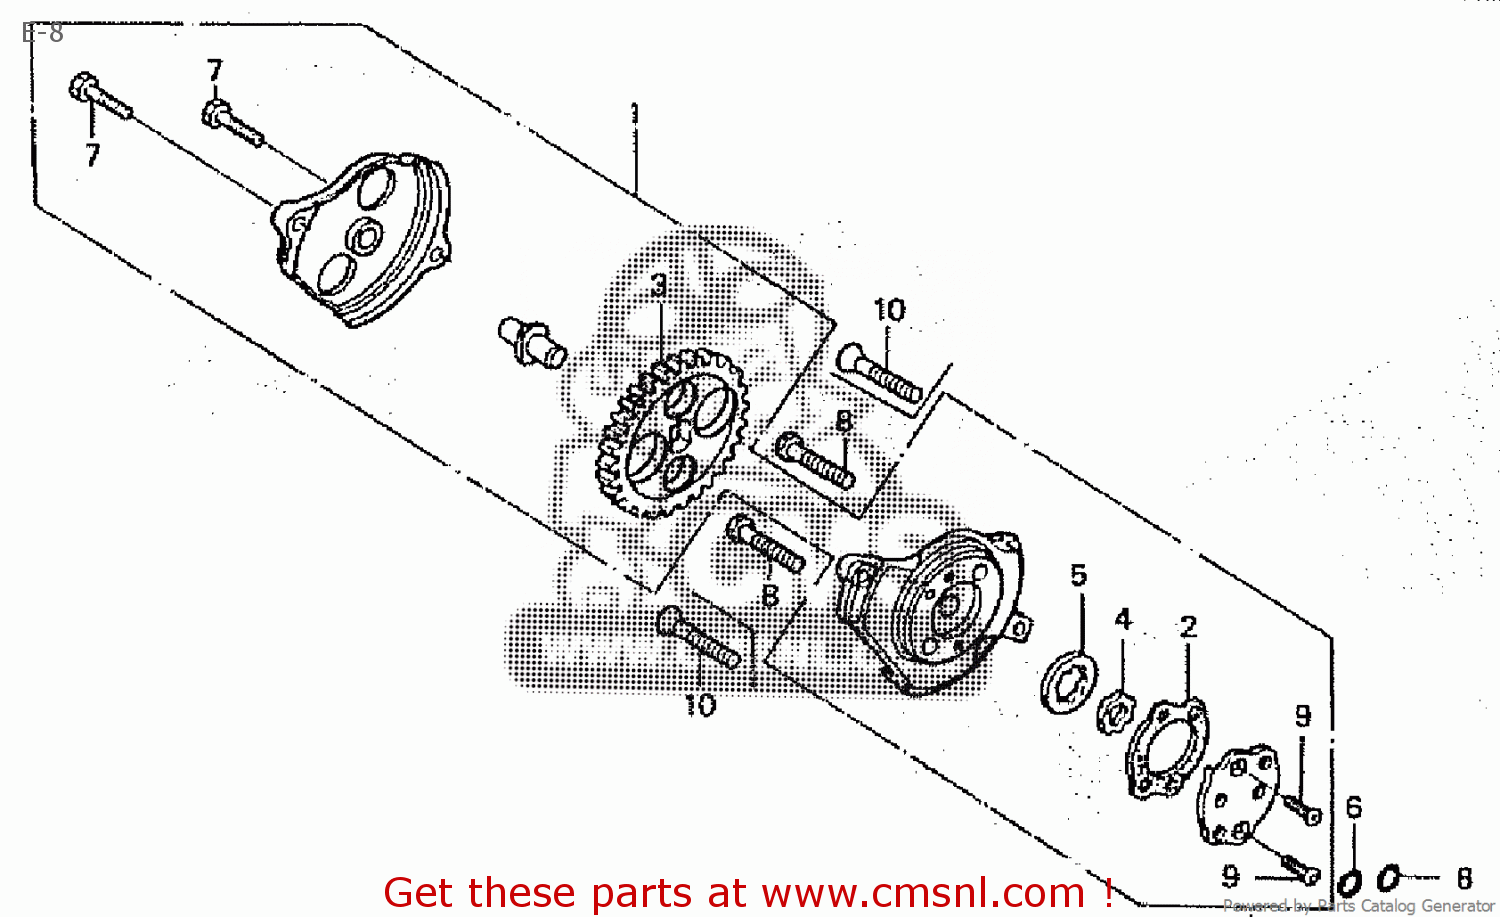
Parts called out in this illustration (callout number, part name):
1	PUMP ASSY.,OIL
2	GASKET,OIL.POMP (NAS)
3	GEAR,OIL PUMP
4	ROTOR,INNER
5	ROTOR,OUTER
6	O-RING,9.4X2.4
7	BOLT,HEX.,5X18
8	BOLT,HEX.,6X22
9	SCREW,FLAT.4X12
